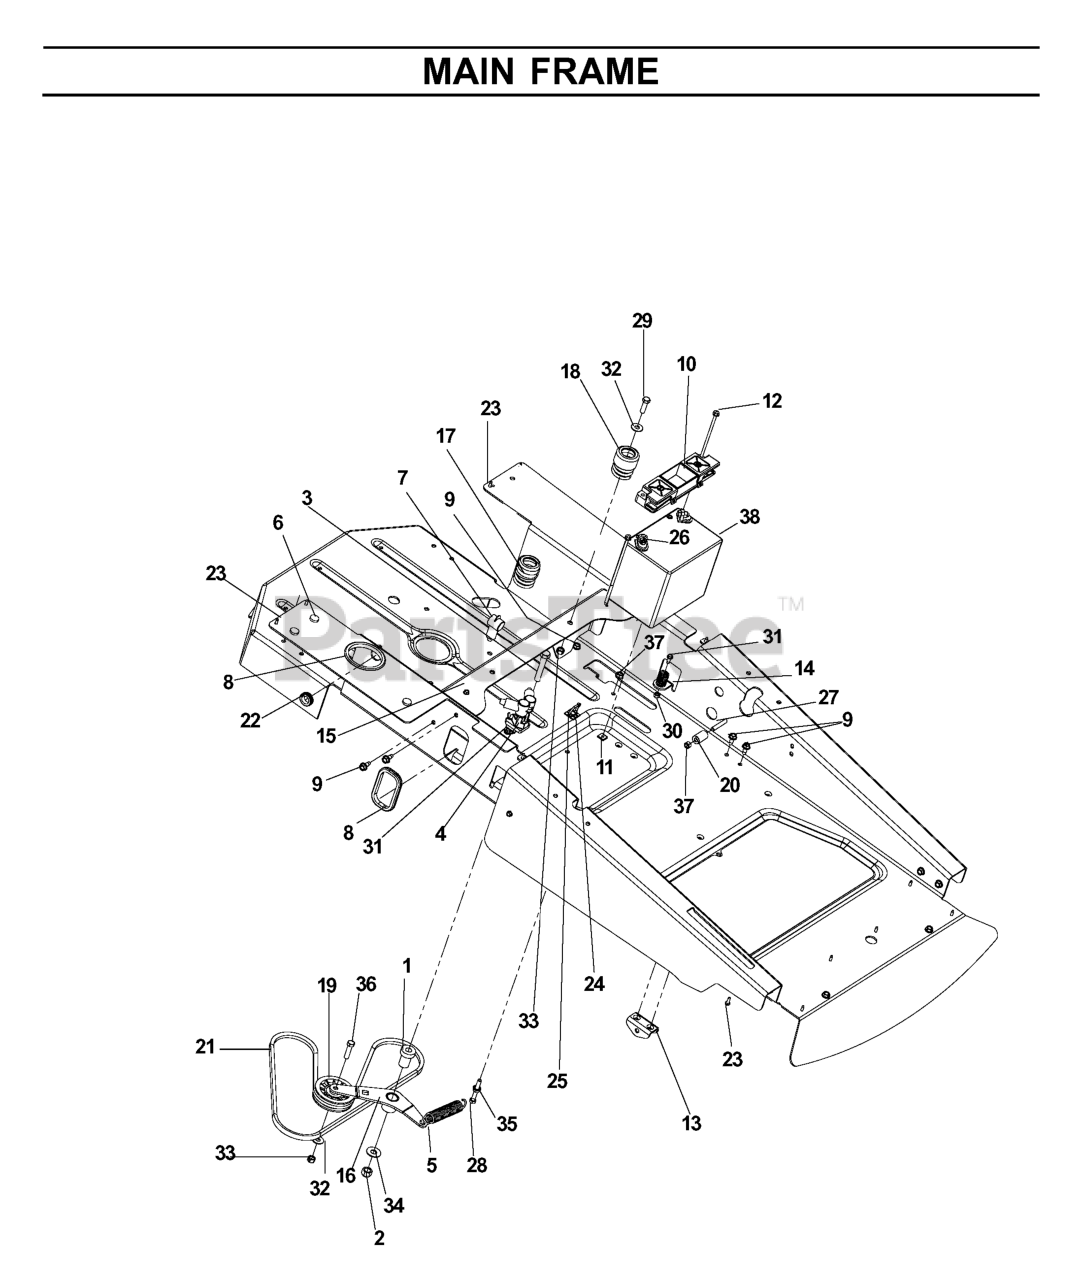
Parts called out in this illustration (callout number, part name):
1	IDLER SPINDLE
2	NUT 1/2-13 HEX NYLOC ZD
3	HCS 1/2C X 2 3/4
6	GROMMET, BUMPER
9	BOLT 5/16-18 X 3/4
10	BATTERY HOLD DOWN
11	PUSH NUT-NYLON
12	BOLT - 1/4-20 X 7.5
13	BRACKET, DECK HANGER
14	SPRING, RETURN TO NEUTRAL
15	REAR SEAT SUPPORT ORANGE
16	PUMP IDLER WELDMENT
17	SPRING, SEAT
18	CAP, SPRING COVER
19	PULLEY, IDLER RAKE & ZTR
20	MOTION LIMITER
21	BELT, HYDRO PUMP
22	GROMMET, FUEL LINE
23	SCR #10-12X1-1/2HEX WASH HD ZD
24	MOUNTING BLOCK CABLE TIE
25	TIE, PLASTIC
26	HCS 5/16C X 3/4
27	HCS 5/16-18X2
29	HCS 3/8C X 1 1/4 GR5
30	NUT.1/4-20.HEX.NYLOC.ZD
31	SCREW 1/4 X 5/8
32	WASHER 3/8 FLAT
33	NUT 3/8C CENTERBLOCK
34	WASHER 1/2 FLAT
35	NUT 5/16C WHIZ
36	HCS 3/8C X 1 1/2
37	NUT 5/16 NYLOC
38	BATTERY, 12 V 330 AMP
